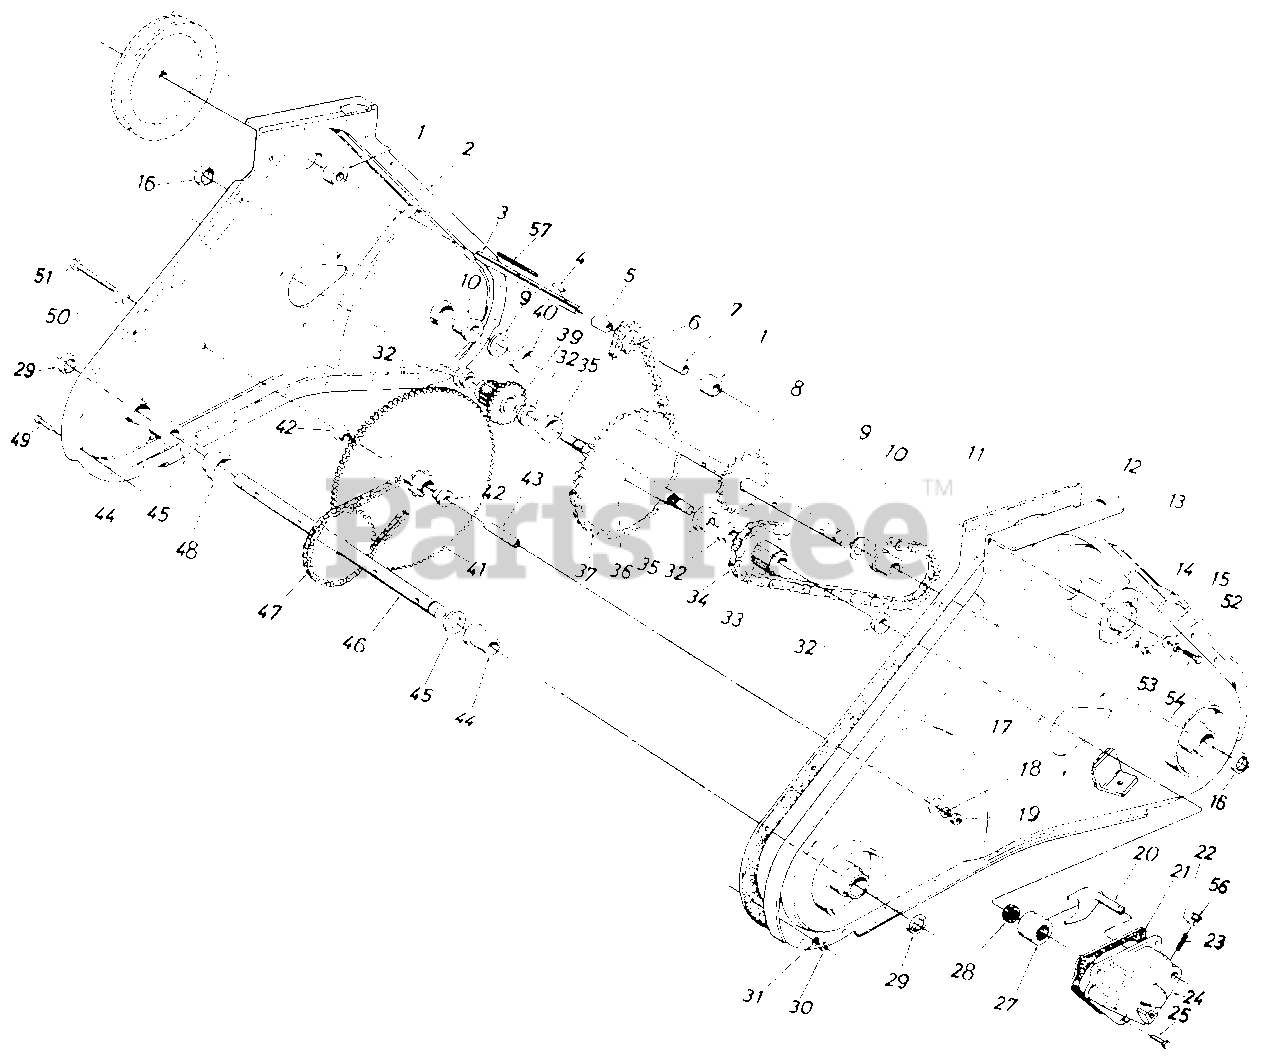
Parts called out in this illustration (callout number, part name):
1	Ball Bearing .62" I.D. x 1.38" O.D. x .44
2	Chain Case R.H. Half
3	Input Shaft .62" Dia.
4	Sq. Key 3/16" x 3/16" x .75" Lg.
5	Spacer .637" I.D. x .781" O.D. x.85" Lg.
6	Sprocket 9 Tooth x .62" Shaft
7	Spacer .637" I.D. x .781" O.D. x 1.44" Lg.
8	Tine Shaft Ass'y.
9	Fl-Wash. 1.28" I.D. x 1.62" O.D.
10	Flange Bearing 1.25" I.D.
11	Gasket-Housing
12	Chain Case L.H. Half
13	Bearing Housing 1-3/8" O.D.
14	L-Wash. 1/4" I.D.
15	Hex Nut 1/4-28 Thd.
16	Seal 1.25" I.D.
17	Belleville Wash.
18	L-Wash. 3/8" I.D.
19	Hex Cent. L-Nut 3/8-24 Thd.
20	Shift Yoke Ass'y.-L.H.
21	Gasket-Shift Housing
22	Ball Detent .250 Dia.
23	Compression Spring
24	Shift Housing-L.H.
25	Hex Tap-Tite 5/16-18 x .75" Lg.
27	Clutch Dog
28	Clutch Dog Driver
29	Seal 1.0" I.D. x 1.38"0.D.
30	Hex Nut 1/4-28 Thd.*
31	L-Wash. 1/4" I.D.*
32	Flange Brg. 1.0O" I.D.
33	Sprocket Brg. Sleeve Ass'y.
34	#50 Chain-5/8" Pitch x 50 Links-Endless
35	Stepped Spacer 1.0" l.p. x 1.75" O.D.
36	Clutch Shaft Ass'y.
37	#420 Chain 1/2" Pitch x 58 Links-Endless
39	Gear Bearing-Sleeve Ass'y.
40	Spacer 1.25" I.D. x 2.0" O.D. x .68" Lg.
41	Sprocket and Gear Ass'y.
42	Flange Brg. .628" I.D. x 753n O.D.
43	Hub Sleeve 88" I.D. x .625" O.D.
44	Flange Brg. 1.00" I.D. x 1.188" O.D.
45	Fl-Wash. 10" I.D. x 1.62" O.D.
46	Axle Shaft Ass'y.
47	#420 Chain 1/2" Pitch 46 Links-Endless
48	Spacer 1.0" I.D. x 2. 0" O.D.
49	Hex Bolt 1/4-28 x .62" Lg.
50	Belleville Wash.
51	Hex Bolt 3/8-24 x 2.75" Lg.*
52	Fl-Wash. 5/16" I.D.
53	L-Wash. 5/16" I.D.*
54	Hex L-Bolt 5/16-24 x .75" Lg.
56	Cap Plug .250" Dia.
57	Sq. Key 8/16" x 2.0" Lg.
